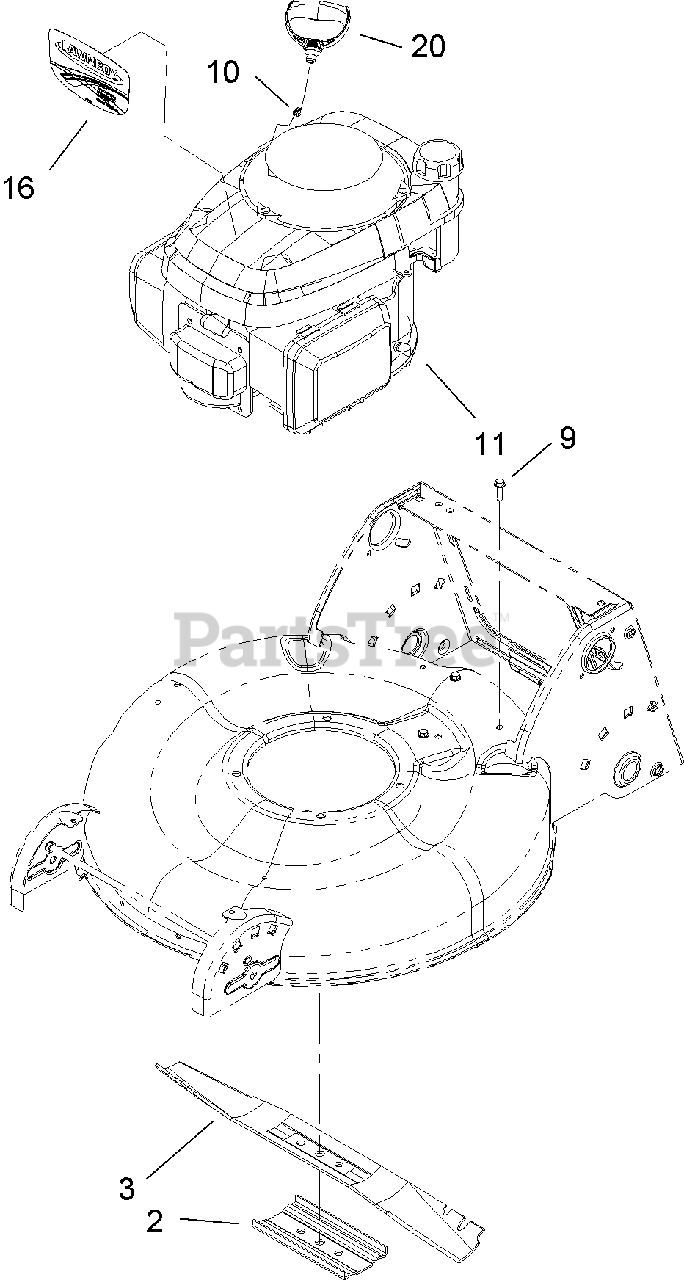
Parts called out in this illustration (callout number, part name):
2	SUPPORT-BLADE
3	BLADE-21 IN
9	SCREW-HWH
10	STOP-ROPE
20	HANDLE-RECOIL
